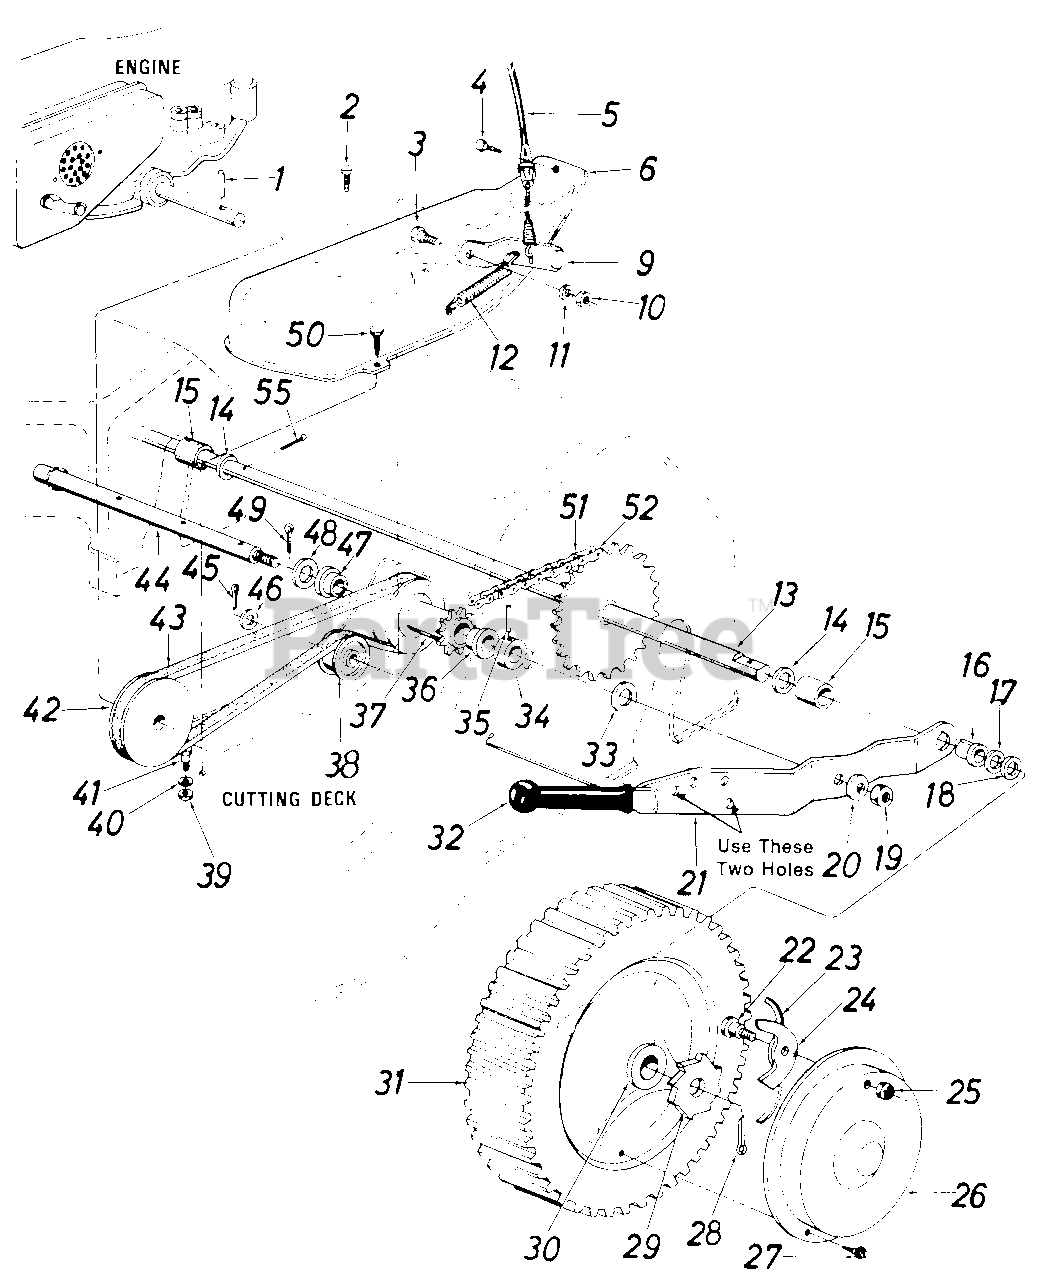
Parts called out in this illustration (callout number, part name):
1	Spring Pin Roll 3/16 Dia. x 1.50
2	Hex Wash. S. Tap Scr. 1/4-20 x .75" Lg.
3	Shld. Scr. .375 Dia. x .181
4	Hex Drilling Scr. #10 x .50" Lg.
5	Clutch Control Cable
6	Belt Cover
9	Idler Brkt. Ass'y.
10	Hex Nut 1/4-20 Thd.
11	L-Wash. 1/4" Scr.
12	Extension Spring .33 O.D. x 1.12 Lg.
13	Rear Shaft Ass'y.
14	Fl-Wash. .510 I.D. x 1.00 O.D.
15	Spacer .765 I.D. x .89 O.D. x .96" Lg.
16	Flange Brg. .506 I.D.
17	Fl-Wash. .531 I.D. x .93 O.D.
18	Fl-Wash. .531 I.D. x .93 O.D.
19	Hex Jam Nut 3/8-16 Thd.
20	Bell-Wash. .400 I.D. x .88 O.D. x .060
21	Rear Wheel Pivot Brkt. Ass'y.
22	Shld. Scr. .342 Dia. x .268
23	Spring Nylon
24	Pawl
25	Hex Ins. L-Nut 1/4-20 Thd.
26	Hub Cap
27	Pan Hd. Tap Scr. #12 x .50" Lg.
28	Cotter Pin 1/8 Dia. x 1.00" Lg.
30	Flange Bearing
31	Wheel Ass'y. Comp. - Rear
33	Bell-Wash. .400 I.D. x 1.13 O.D. x .040
34	Spacer .505 I.D. x .88 O.D. x .440
35	Spring Pin Roll 3/16 Dia. x 1.00" Lg.
36	Flange Brg. .506 I.D. - Plastic
37	Pulley w/9 Tooth Sprocket Ass'y.
38	Plastic Flat Idler
39	Hex Nut 5/16-18 Thd.
40	L-Wash. 5/16" Scr.
41	Shld. Scr. .437 Dia. x .350
42	Engine Pulley
43	"V"-Belt 1/2 x 33" Lg.
44	Pulley Shaft
45	Cotter Pin 1/8 Dia. x 1.00" Lg.
46	Fl-Wash. .531 I.D. x .930 x .050
47	Flange Brg. .506 I.D.
48	Fl-Wash. .531 I.D. x .930 x 050
49	Cotter Pin 3/32 Dia. x 1.00" Lg.
50	Hex Wash. Self-Tap Scr. 1/4-20 x .50" Lg.
51	#48 Chain 1/2" Pitch x 31 Links
52	#48 Master Link 1/2" Pitch
55	Cotter Pin 3/32" Dia. x 1.00" Lg.
